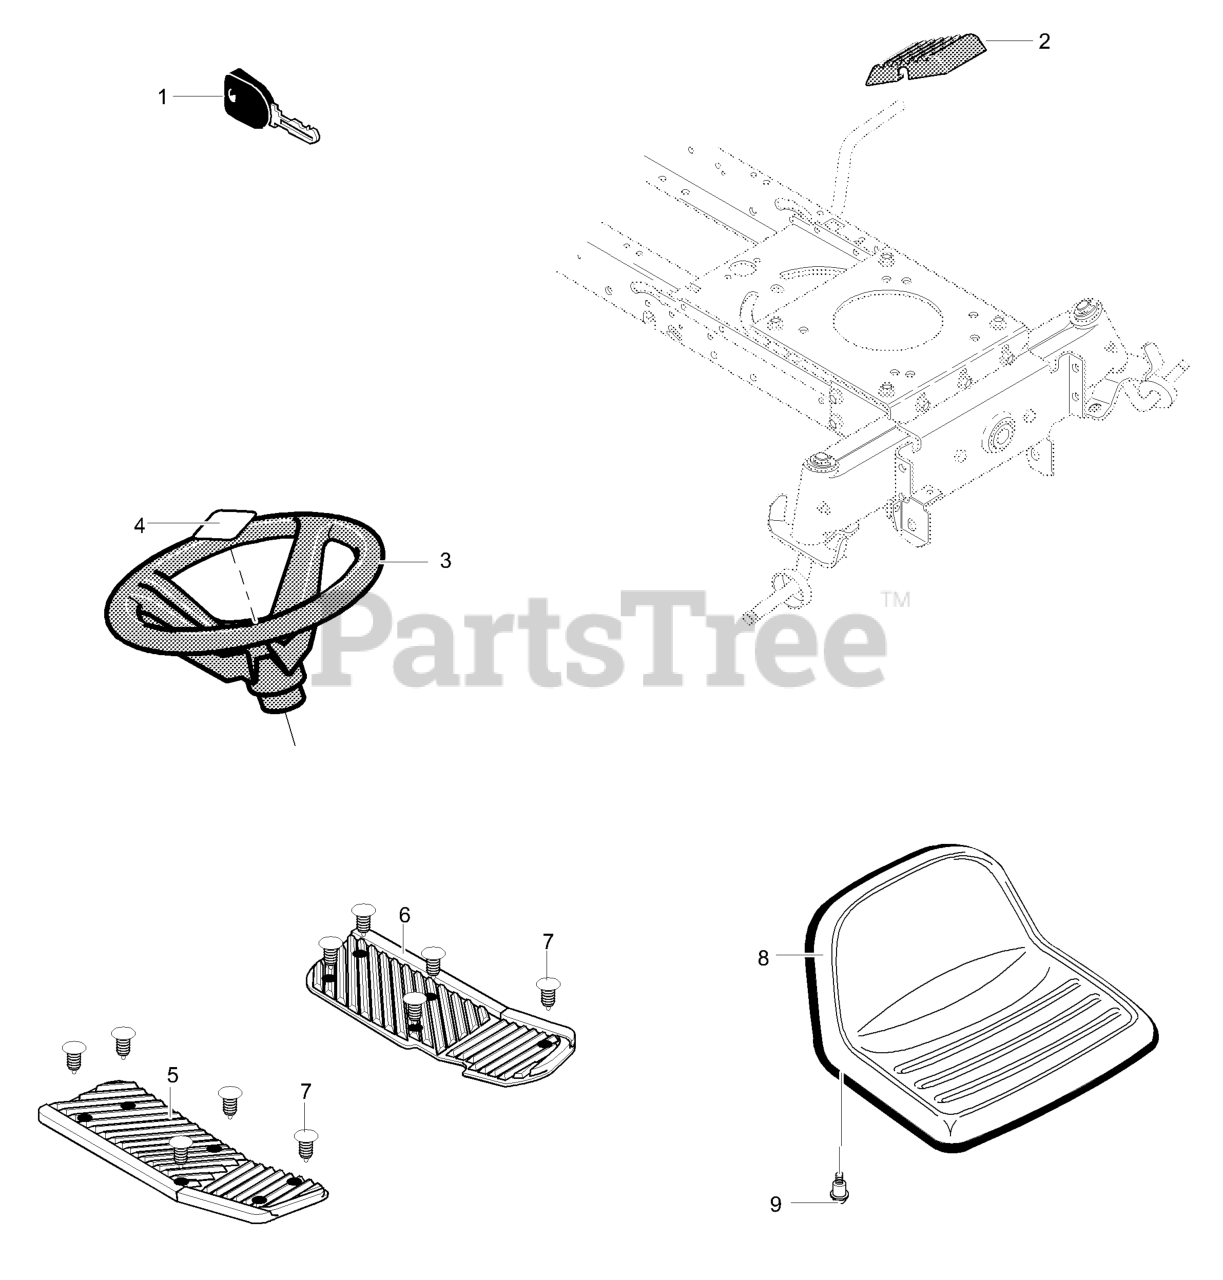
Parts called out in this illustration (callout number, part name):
1	Ignition Key
2	Pad, Brake/Clutch
3	Steering Wheel
4	Insert, 4-Spoke
5	Foot Pad RH
6	Foot Pad LH
7	Ratchet Fastener
9	BOLT, Shoulder 5/16-18
